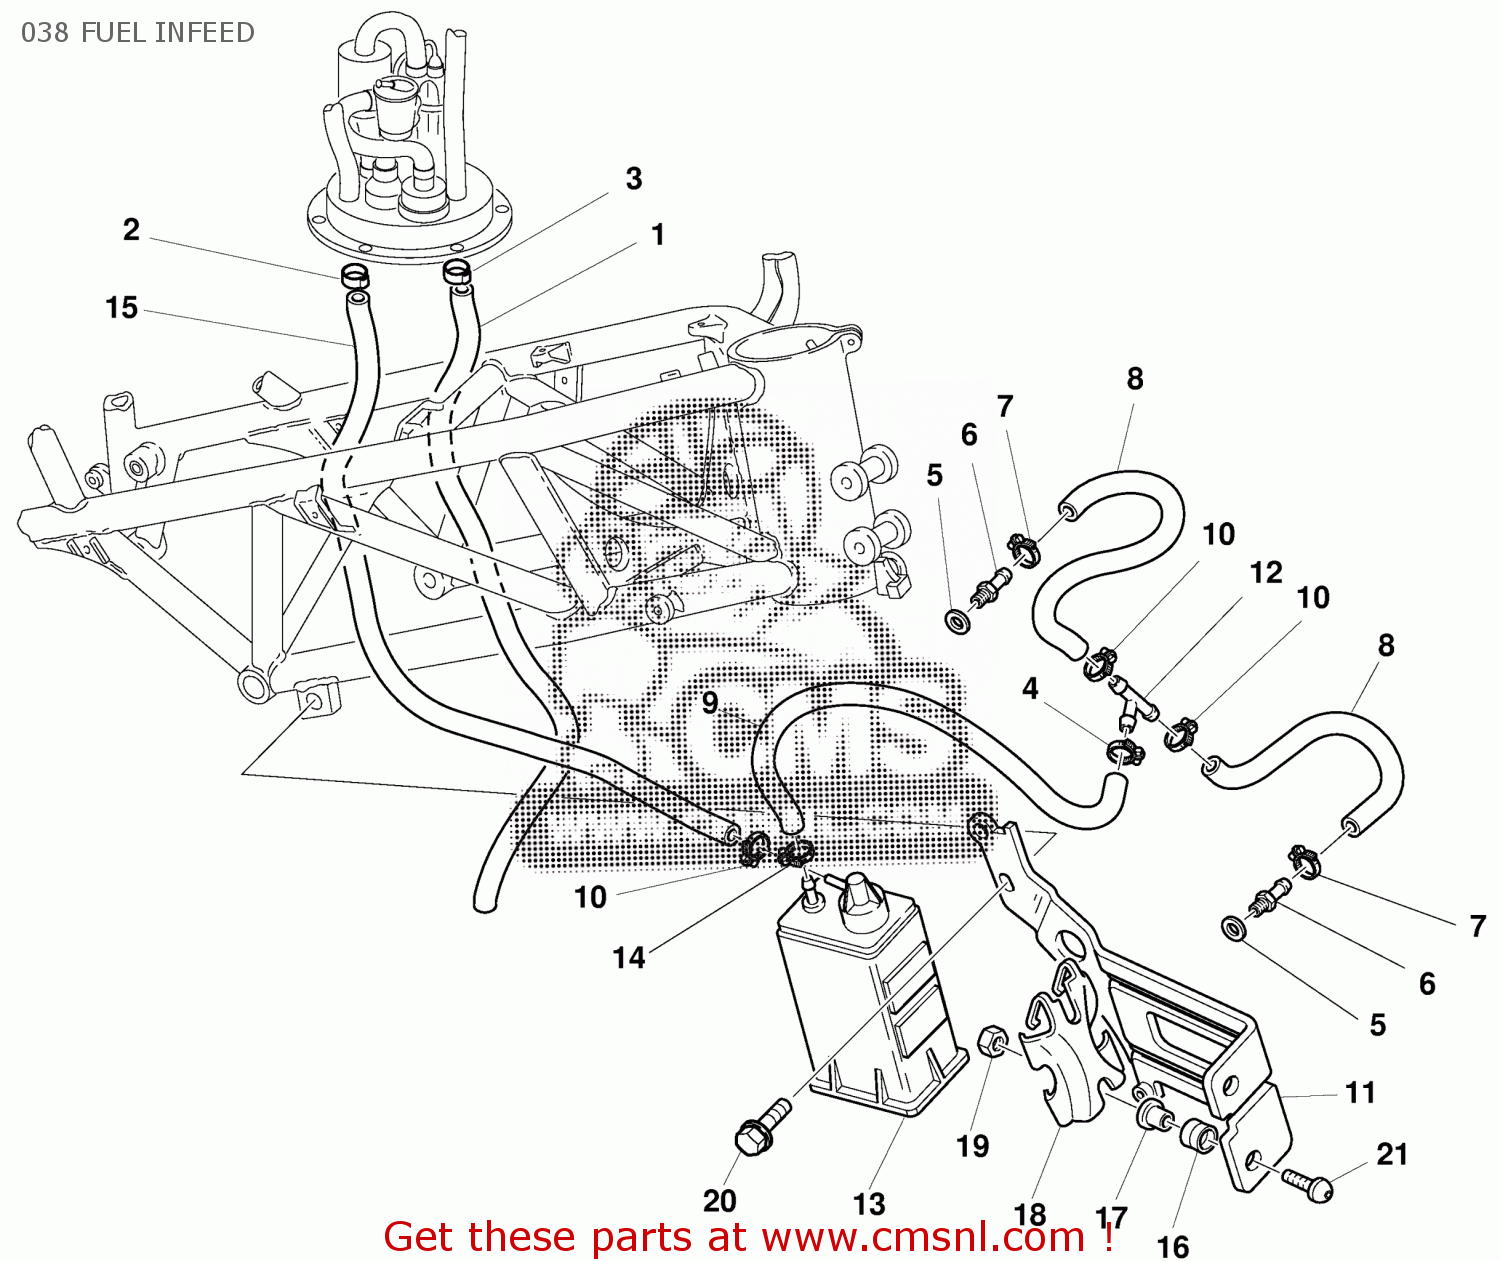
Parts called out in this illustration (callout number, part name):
1	BREATHER PIPE
2	CLAMP
3	CLAMP
4	CLAMP
5	ALUMINIUM GASKET
6	UNION
7	CLAMP
8	FUEL PIPE 7X13X185
9	TUBE 4X9X410 996/01 USA
10	CLAMP
11	HOLDER
12	THREE-WAYS UNION
13	CANISTER FILTER
14	CLAMP
15	PIPE
16	RUBBER PAD
17	SPACER
18	PLATE
19	NUT
20	SCREW TEF M6X1.00X14 CH8
21	SCREW
